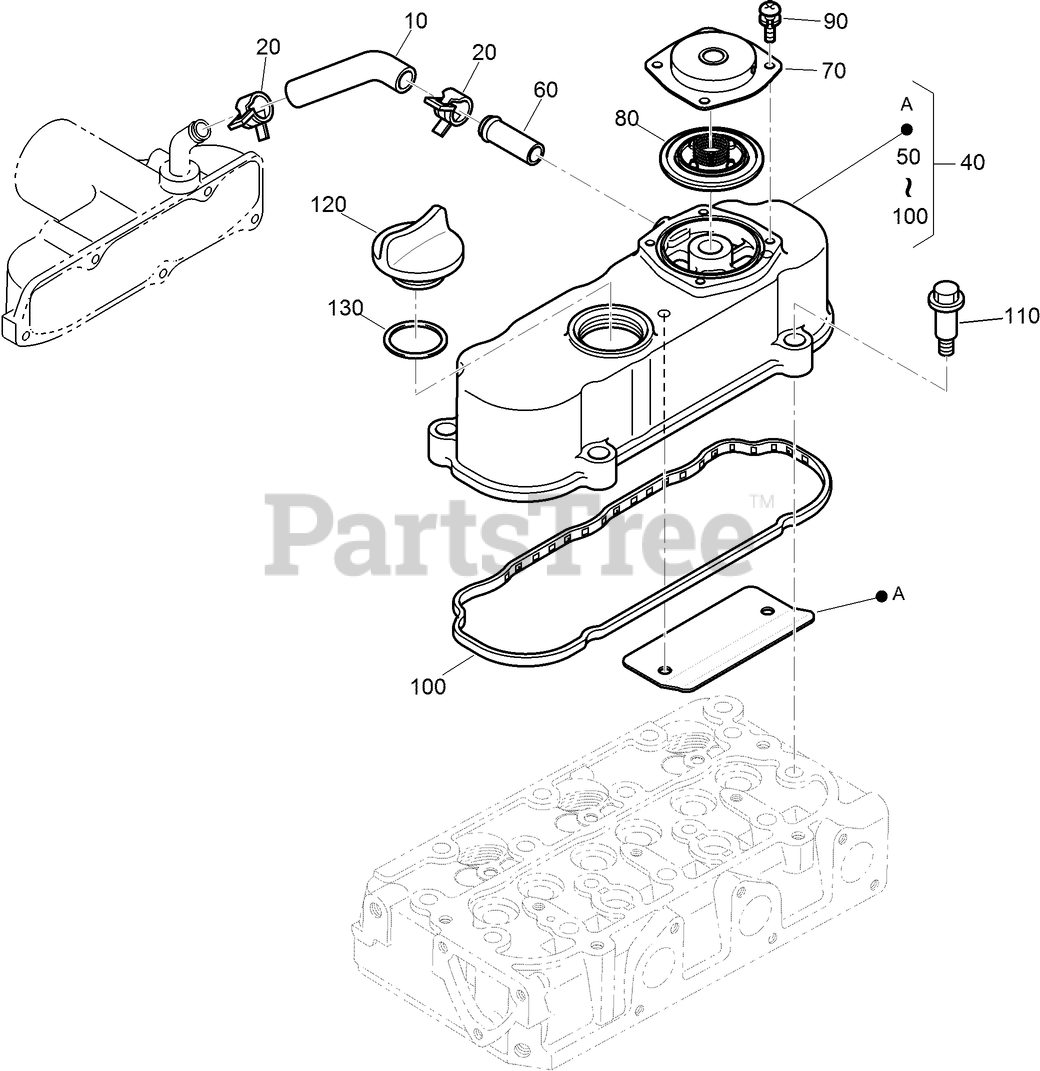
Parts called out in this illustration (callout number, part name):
10	TUBE-BREATHER
20	CLAMP-HOSE
40	COVER-CYLINDER HEAD
50	CYLINDER HEAD ASM
60	PIPE-RETURN, WATER
70	COVER-BREATHER
80	VALVE-BREATHER
90	SCREW (WITH WASHER)
100	GASKET-COVER, HEAD
120	PLUG-FILLER, OIL
130	O-RING
